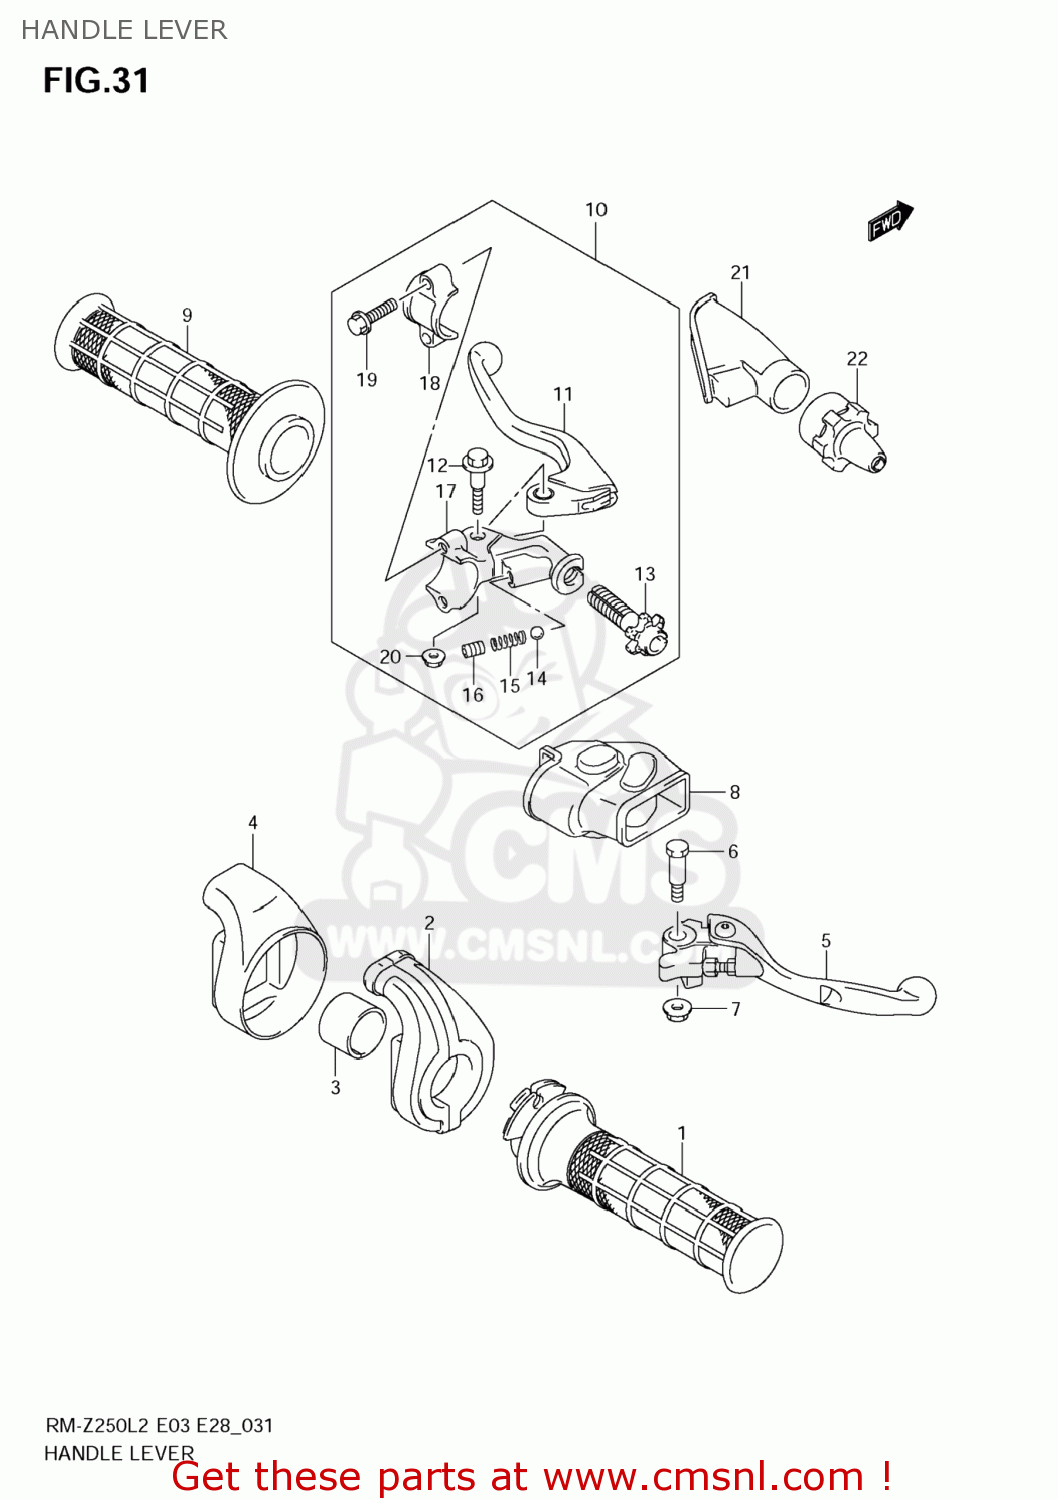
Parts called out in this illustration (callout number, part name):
1	GRIP,THROTTLE
2	CASE ASSY,THROTTLE
3	COLLAR,THROTTLE CASE
4	COVER,THROTTLE CASE
5	LEVER ASSY,BRAKE
6	BOLT,BRAKE LEVER
7	NUT
8	COVER,BRAKE LEVER
9	GRIP,L
10	LEVER ASSY,CLUTCH
11	LEVER,CLUTCH
12	BOLT
13	ADJUSTER,CLUTCH CABLE
14	BALL
15	SPRING
16	SCREW(6X8)
17	HOLDER,CLUTCH LEVER
18	BRACKET,CLUTCH LEVER HOLDER
19	BOLT,BRACKET
20	NUT
21	COVER,CLUTCH LEVER
22	COVER,CLUTCH ADJUSTER
